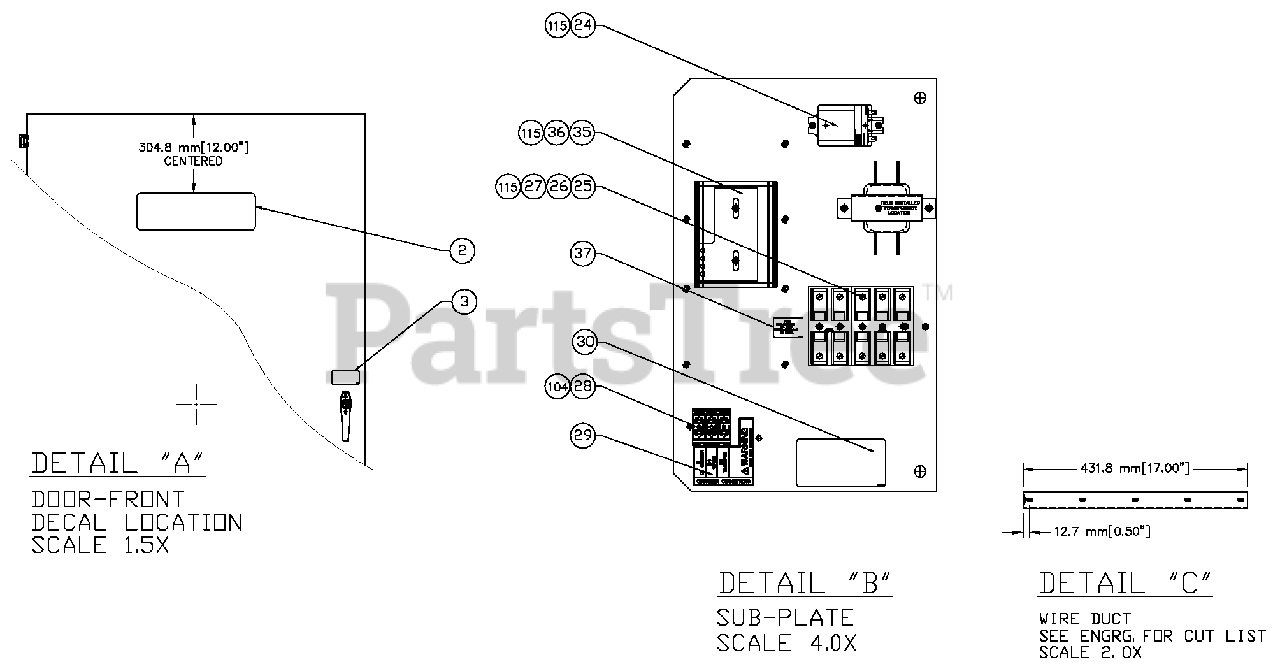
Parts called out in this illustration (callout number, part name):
3	DECAL LIVE CIRCUIT
27	FUSE 5A X BUSS
29	DECAL CUSTOMER CONN.
30	DECAL DANGER HIGH VOLTAGE
35	CHANNEL SNAPTRACK 76.2 X 101.2
36	ASSY LOAD MGMT CONTROLLER
37	DECAL, FUSE RATING 5A 600V
104	SCREW PHTT M3-0.5 X 25 ZINC
115	SCREW PHTT M4-0.7 X 12 ZP
